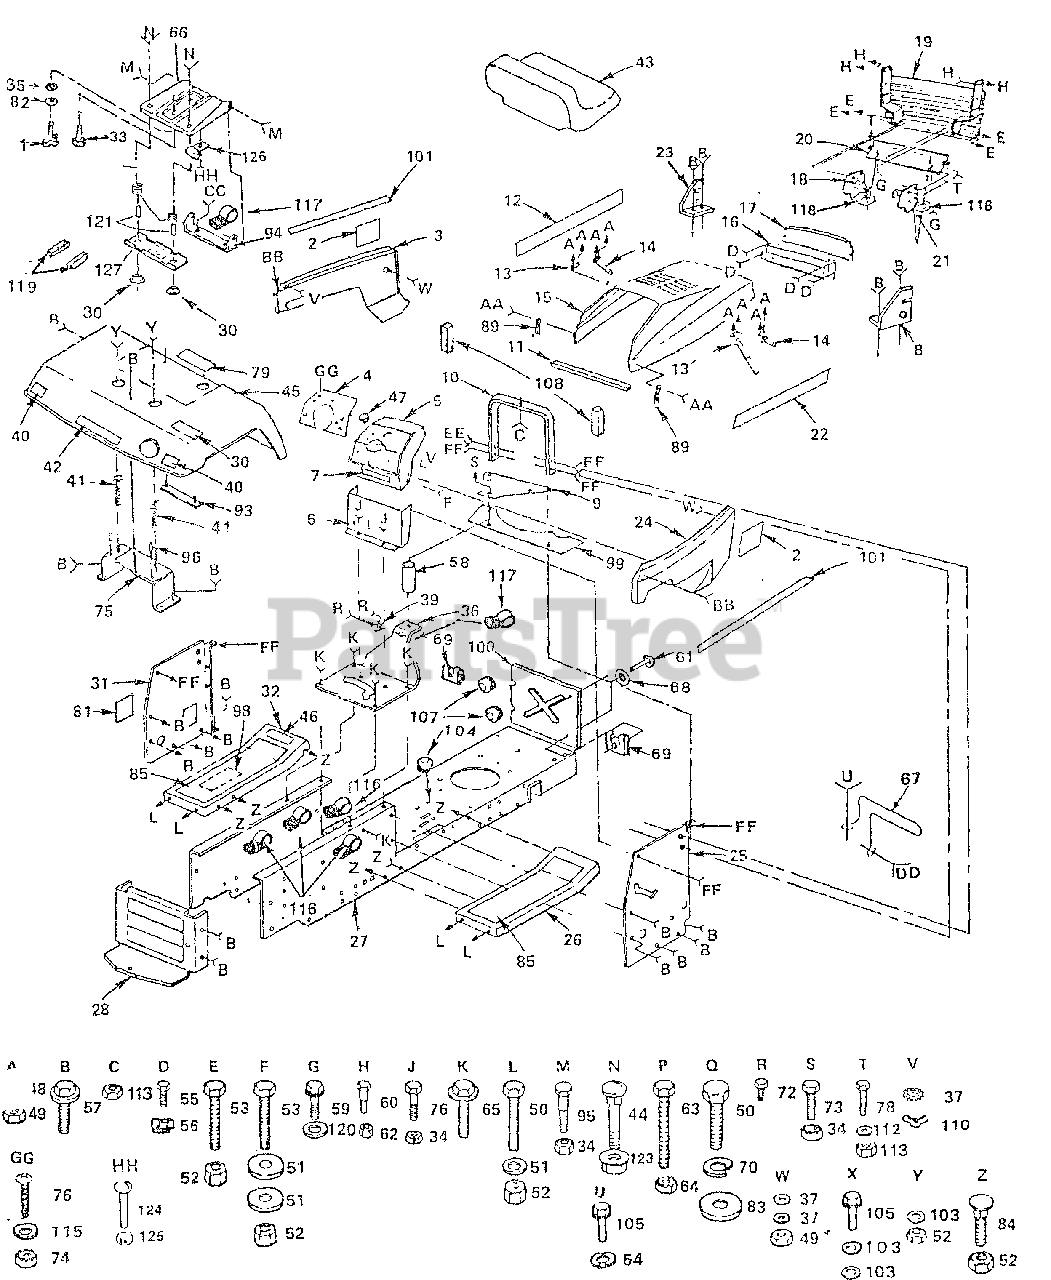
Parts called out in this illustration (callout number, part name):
1	Adjustment Knob
2	Decal - Side Panel
3	Panel - Side, L.H.
4	Dash Plate
5	Dashboard
6	Dash Assembly - Lower
7	Decal - Instruction
8	Bracket Assembly R.H.
9	Plate - Support, Battery
10	Support Assembly - Dash
11	Foam Strip
12	Decal - Hood, L.H.
13	Strap Assembly - Hinge, Rear
14	Strap Assembly - Hinge, Front
15	Hood
16	Bezel Assembly
18	Support- Grill, L.H.
19	Grill Assembly
20	Strap - Grill
21	Support - Grill, R.H.
22	Decal - Hood, R.H.
23	Bracket Assembly L.H.
24	Panel - Side, R.H.
25	Panel - Dash, R.H.
26	Footrest-R.H.
28	Drawbar
30	Bushing Snap
31	Panel - Dash, L.H.
32	Footrest-L H
33	Shoulder Bolt
34	Locknut - Gripco, 5/16-18
35	Washer 15/32 x 1 x 16 Ga.
37	Lock Washer 1/4 Int./Ext.
39	Bushing - Steering
40	Reflector - Tail light
41	Spring - Compression
42	Decal-Fender
43	Seat
44	Bolt, Roundhead 1/4 - 20 x 1 1/4
46	Decal - Clutch/Brake
47	Plug - Button
48	Washer- Lock 1/4
49	Wing Nut 1/4 -20
50	Bolt - Hex 3/8 -16 x 3/4
51	Washer 13/32 x 13/16 x 12 Ga.
52	Nut - Crownlock 3/8 - 16
53	Bolt- Hex 3/8 - 16 x 1
54	Washer 13/32 X 1 X 16 Ga.
55	Screw - Hex Washer Hd. Tapping 10 - 16 x 5/8
56	"J" Fastener
57	Screw - Hex Washer Hd. Thd. Rolling 3/8 - 16 x 3/4 Type TT
59	Screw - Hex Washer Hd. Thd. Rolling 5/16-18 x 3/4 Type TT
60	Bolt - Shoulder 1/4-20
61	Stud 1/4 Turn
62	Nut - Crownlock 1/4 - 20
63	Bolt- Hex 3/8 - 16 x 1-1/4
64	Nut - Keps 3/8-16
65	Screw - Hex Washer Hd. Thd. Forming -318 -16 x 1/2 Type TT
66	Pan - Seat
67	Muffler Guard
68	Retainer- 1/4 Turn
69	Receptacle - 1/4 Turn
70	Washer -Lock,3/8
72	Screw - Hex Head Self Tapping, No. 10 -16 x 1/2 Type B
73	Bolt-Hex 5/16-18 x 2 Gr 2
74	Nut - Keps 5/16-18
75	Bracket Assembly - Fender
76	Screw - Mach. 5/16-18 x 3/4
78	Screw-Hex Washer Hd. 1/4-20 x 3/4
79	Decal - OPEI, Caution
81	Cover-Access
82	Washer- 17/32 x 1-1/16 x 20 Ga.
83	Washer 13/32 x 3/4 x 12 Ga.
84	Bolt - Carriage 3/8 - 16 x 3/4
85	Pad - Footrest
89	Latch - Hood
93	Strap Assembly - Fender
94	Bracket - Pivot, Seat
95	Nut - Push
96	Bolt - Shoulder 5/16-18
98	Decal - V-Belt Drive, Schematic, Tractor
99	Baffle-Rear, Upper
100	Battle-Rear, Lower
100	Wing Nut 1/4-20
101	Decal-Strip
103	Washer 13/32 x 1 x 14 Ga.
105	Screw - Hex Washer Hd., Thd. Rolling 3/8 - 1 6 x 1
106	Washer-Lock 1/4
107	Grommet
108	Foam Strip
109	Lock Washer 1/4 Int. Ext.
112	Washer 9/32 x 3/4 x 16 Ga
113	Nut - Hex 1/4 - 20
115	Washer 11/32 x 11/16 x 16 Ga.
116	Clip - Insulated
117	Clip - Insulated
118	Washer- 11/32 x 3/4 x 12 Ga
119	Foam Strip
120	Washer - 11/32 x 3/4 x 16 Ga.
121	Spacer Split - 0.28 x 0.88
122	Spring - Compression
123	Nut- Hex, Flanged 1/4-20 UNC
124	Screw - Slotted Pan Head, #10-32 x 1/2
125	Nut -Keps,#10-32UNF
126	Clip - Insulated
127	Bracket-Switch Mount
